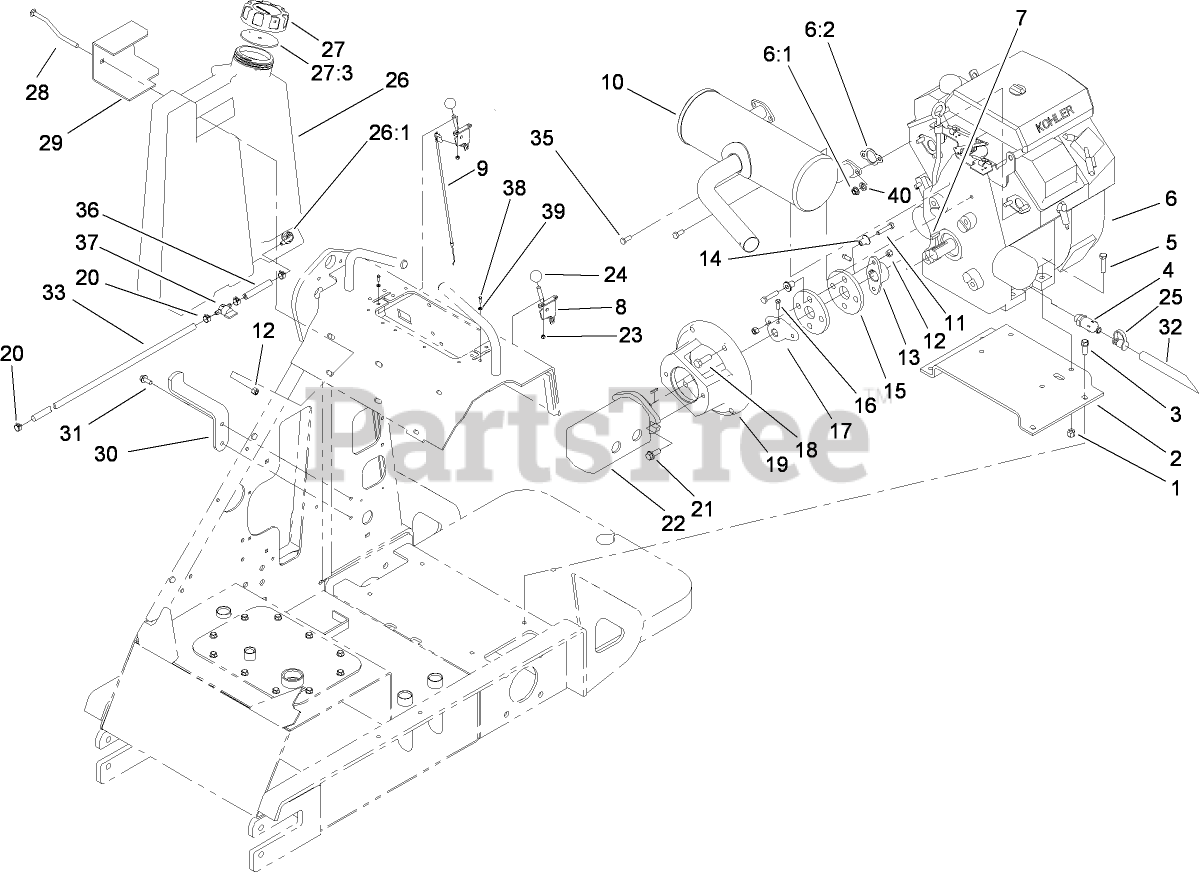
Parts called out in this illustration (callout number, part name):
1	NUT-LOCK, NI
2	MOUNT-ENGINE
3	SCREW-TAPTITE
4	VALVE-DRAIN, OIL
5	SCREW-HH
6	ENGINE-KOHLER, CH20S 64763
6:1	NUT-HF
6:2	GASKET-EXHAUST
7	KEY-SQUARE
8	LEVER-CONTROL
9	CABLE-CONTROL
10	Muffler
11	SCREW-HH
12	NUT-LOCK, NI
13	HUB-ENGINE
14	SPACER
15	COUPLING-RUBBER
16	SCREW-SQH
17	HUB-PUMP
18	SCREW-HH
19	MOUNT-PUMP
20	CLAMP-HOSE
21	SCREW-HHF
22	HYD PUMP ASM
23	NUT-KEPS
25	CAP-DUST
26	RH Fuel Tank ASM
26:1	FITTING-FUEL, BULKHEAD
27	CAP-FUEL, GAS
27:3	GASKET-VENTED
28	BOLT-MOUNT
29	PLATE-MOUNT
30	MOUNT-BOTTOM, TANK
31	SCREW-HWHTF
33	HOSE-FUEL
35	SCREW-HH
36	HOSE-FUEL
37	VALVE-FUEL
39	WASHER-FLAT
40	WASHER-LOCK
